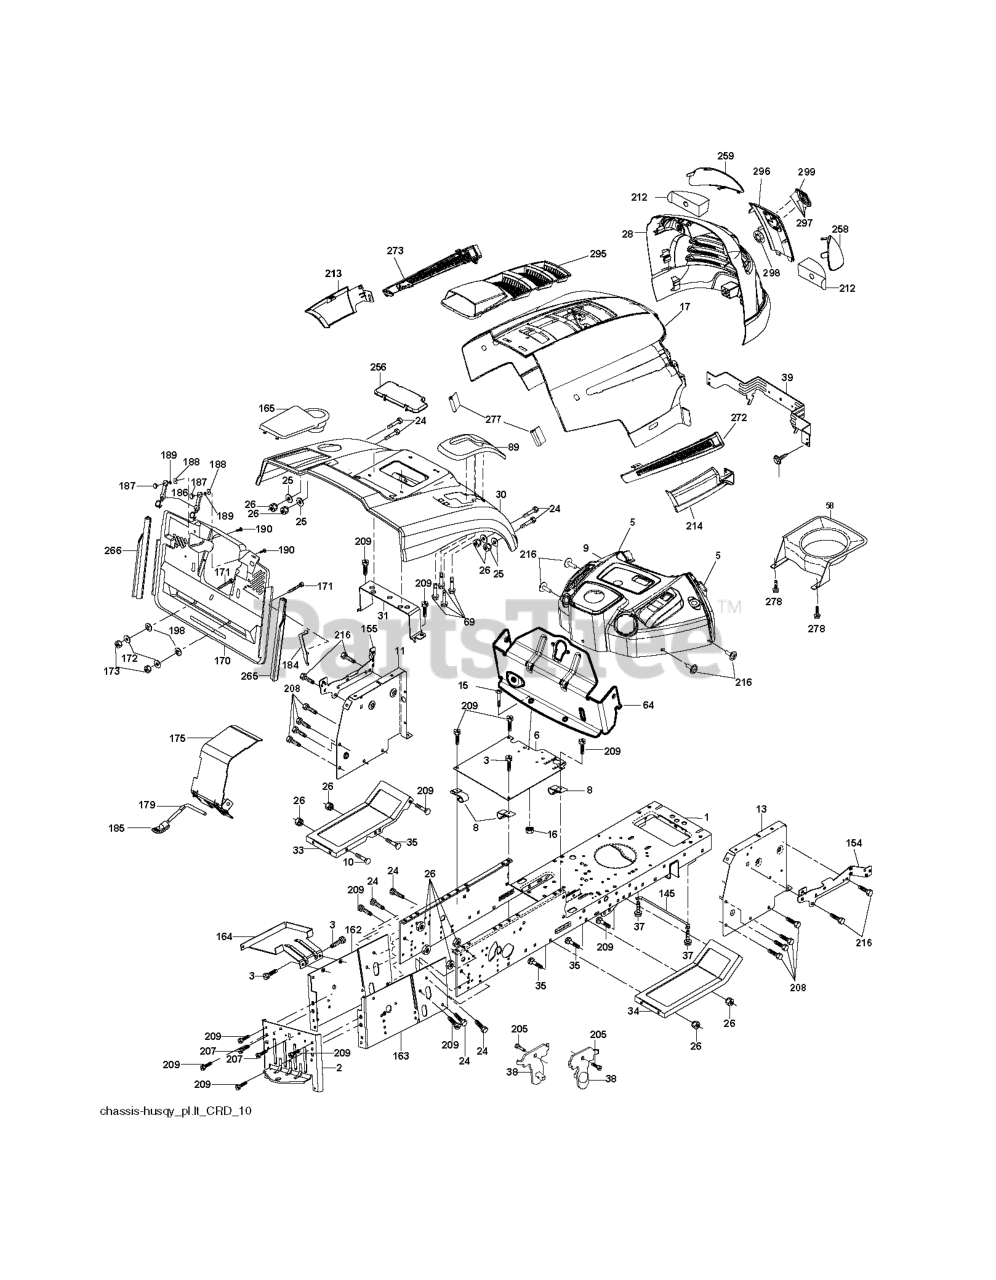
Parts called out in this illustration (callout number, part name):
2	DRAWBAR
3	SCREW 3/8-16X3/4
5	BUMPER.HOOD.TEX.HUSQVARNA
6	PLATE
8	CLIP,INSULATOR
10	BOLT D
11	PANEL.DASH.LH.LTX
13	PANEL ASM, DASH RH
15	Screw, Machine, Truss Head 5/16-18 UNC x 3/4
16	NUT
17	HOOD
25	WASHER
26	NUT
28	RP GRILLE/LENS ASM.
30	CONSOLE.CRD.AUTO.GRY
31	BRACKET SUPPORT FENDER
33	FOOTREST PNT LH
34	FOOTREST PNT RH
37	Screw 5/16-18 x 1/2 Hex, Self Tapping 5/16-18 x 1/2
38	BRACKET ASM PIVOT MOWER REAR
39	BRACKET PIVOT
69	SCREW.HI-LO.CONSOLE
89	CONSOLE.CRD.AUTO.GREY.2005
145	ROD PIVOT CHASSIS/HOOD
162	BRACKET
163	BRACKET EXTEN CHASSIS RH CRD
165	RP.COVER.BATTERY.CRD.GREY
172	WASHER
175	DOOR TRAP
179	ROD PIVOT FBI
184	BRACKET.ACTUATOR.BAGGER.SRD
186	LATCH ASSY
187	WELDNUT
189	LOCKWASHER #10
190	SCREW
207	SCREW, 5/16-18 X 1/2
208	SCREW 3/8-16X1/2
209	SCREW, 3/8-16X3/4
212	INSERT REFLECTIVE
213	SKIRT SIDE LH
214	SKIRT SIDE RH
216	SCREW HEXWSHR 1/4-20X3/4
256	COVER FENDER CRD
258	LENS.HUSQVARNA LT.RH
259	LENS.HUSQVARNA LT.LH
265	SEALING
266	SEALING
272	VENT SIDE HOOD LH
273	VENT SIDE HOOD RH
277	BUMPER DASH
278	SCREW
295	VENT TOP HOOD
296	TRIM
297	CLIP.RETAINER.TINNER.
298	NUT PUSH M
299	RP LOGO
